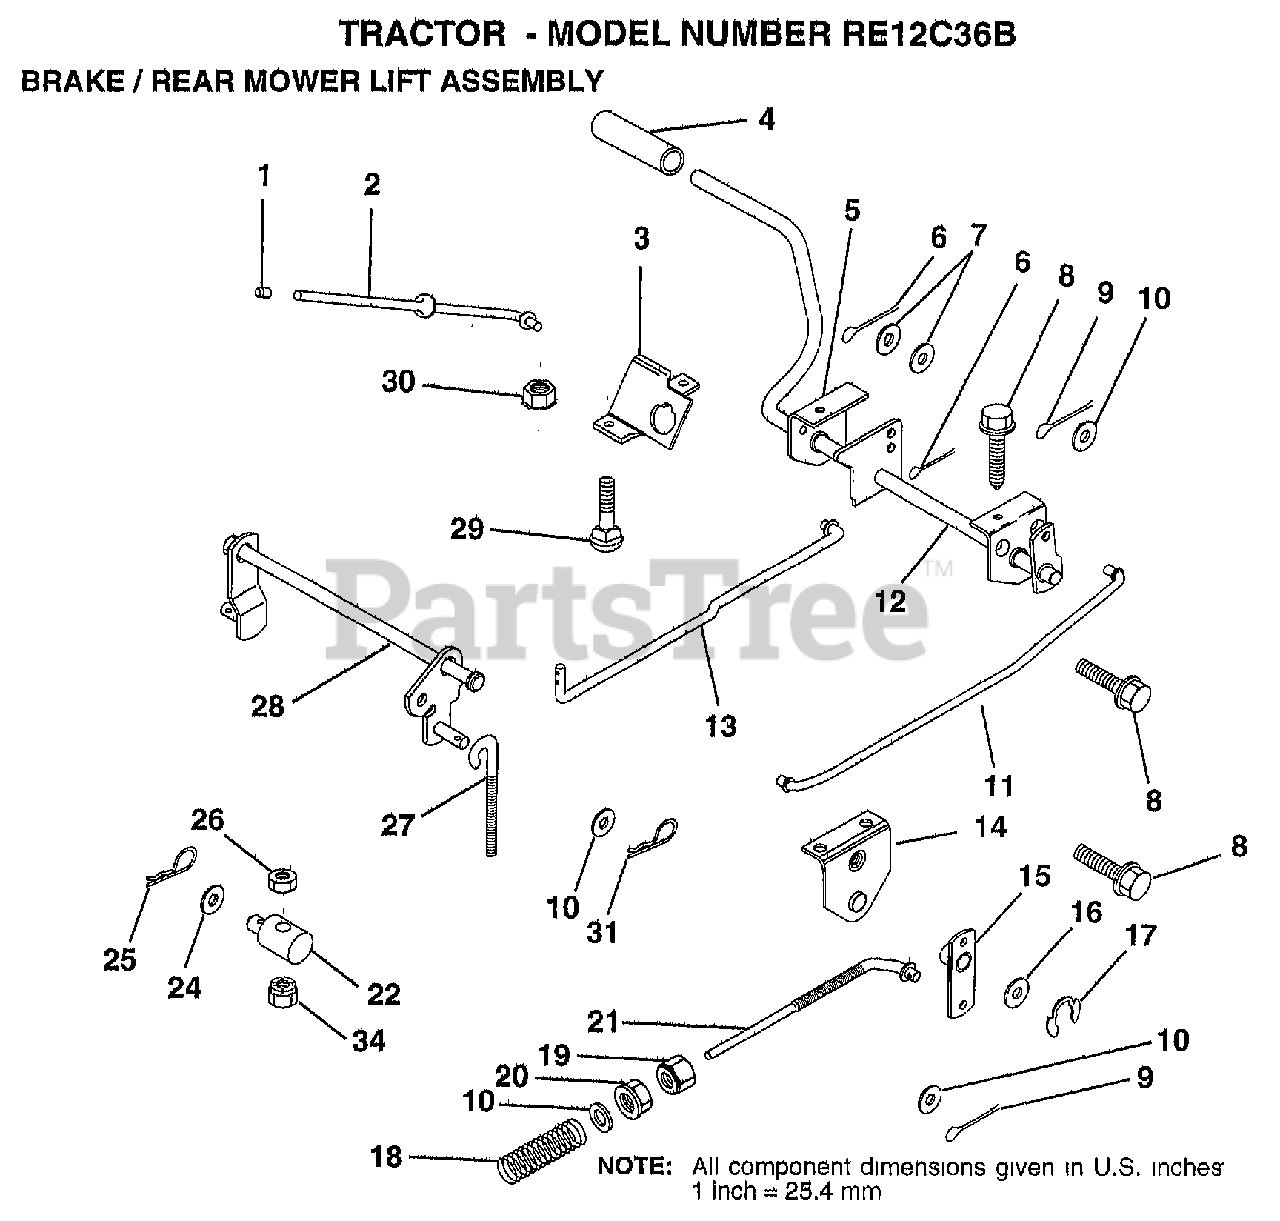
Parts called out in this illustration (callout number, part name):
1	PLUNGER CAP T
2	"ROD,PARK BRAKE"
3	"BRKT,PARK BRAKE"
4	FOOT PEDAL COVER
5	"BRKT,CLU PEDAL LH"
7	WASHER
8	SCREW LT
9	COTTER PIN
10	WASHER
11	"ROD,FRT BRAKE"
12	PEDAL ASM CL/BK36
13	"ROD,CLUTCH"
14	"BRKT,LIFT SHAFT"
15	PVT BRAKE ARM ASM
16	WASHER T
17	KLIP RING
18	SPRING ROD BRAKE
19	NUT
20	NUT
22	TRUNNION.LIFT.
24	WASHER
25	SPRING.RETAINER
26	LOCKNUT
27	"LINK, MOWER REAR"
28	LIFT ASM MOW REAR
31	RETAINER.SPRING
